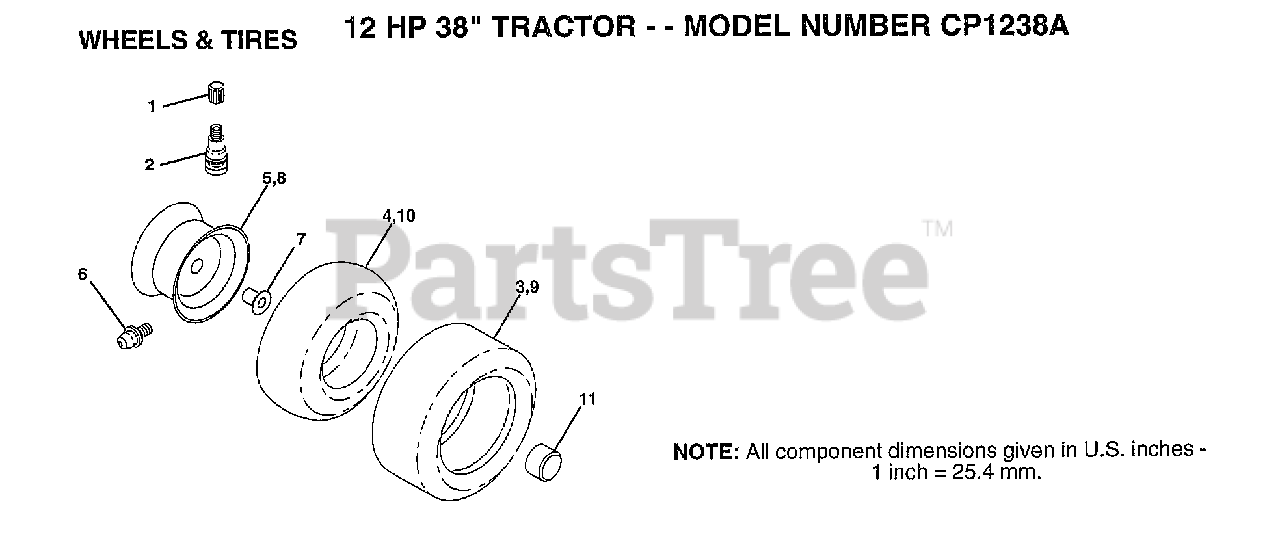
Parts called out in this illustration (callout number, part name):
1	VALVE CAP
2	VALVE STEM LT
4	TUBE.5.3/4.5/6
6	FITTING LT
7	"FLANGE, BEARING"
10	TUBE.18X9.5-8
11	HUB CAP
